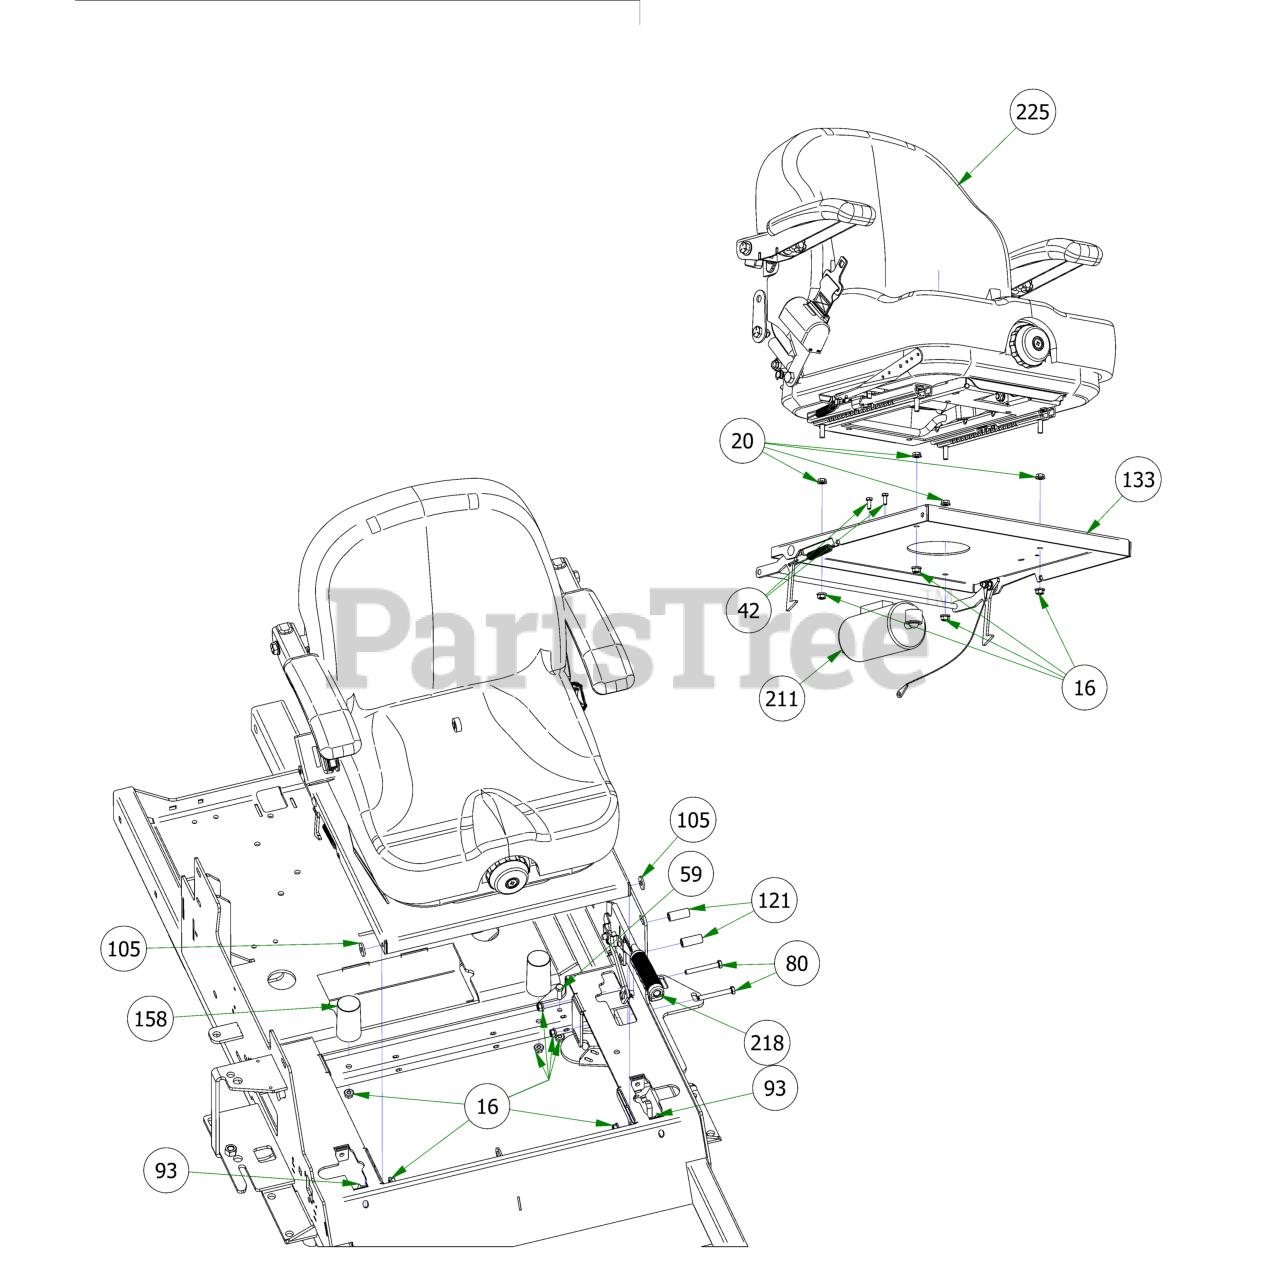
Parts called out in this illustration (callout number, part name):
16	5/16-18 NYLON INSERT FLANGE LOCKNUT ZINC
20	5/16-18 HEX SERRATED FLANGE NUT HARD/ZINC
42	M6-1.0 X 16MM DIN 933 HEX TAP BOLT (CL 8.8) ZINC
59	5/16-18 X 1 HEX CAP SCREW (GR.5) ZINC
80	5/16-18 X 2-1/2 HEX CAP SCREW (GR.5) ZINC
93	5/16-18 X 1 CARRIAGE BOLT (GR.8) ZINC
105	.360 ID X .983 OD X .120 THICK FLAT WASHER NYLON
121	.380 ID X .625 OD X 1.500 LGTH 2019 OUTLAW BRAKE HANDLE SPACER ZINC
133	R-SERIES SEAT PLATE ASSEMBLY
158	2019 Bad Boy X Cylindrical Seat Mount
211	2019 Outlaw EPA Cannister Assembly
218	2019 Brake Handle Assembly
224	2019 Renegade Gas Frame - Powdercoated
225	2022 Suspension Seat w/Seatbelt
